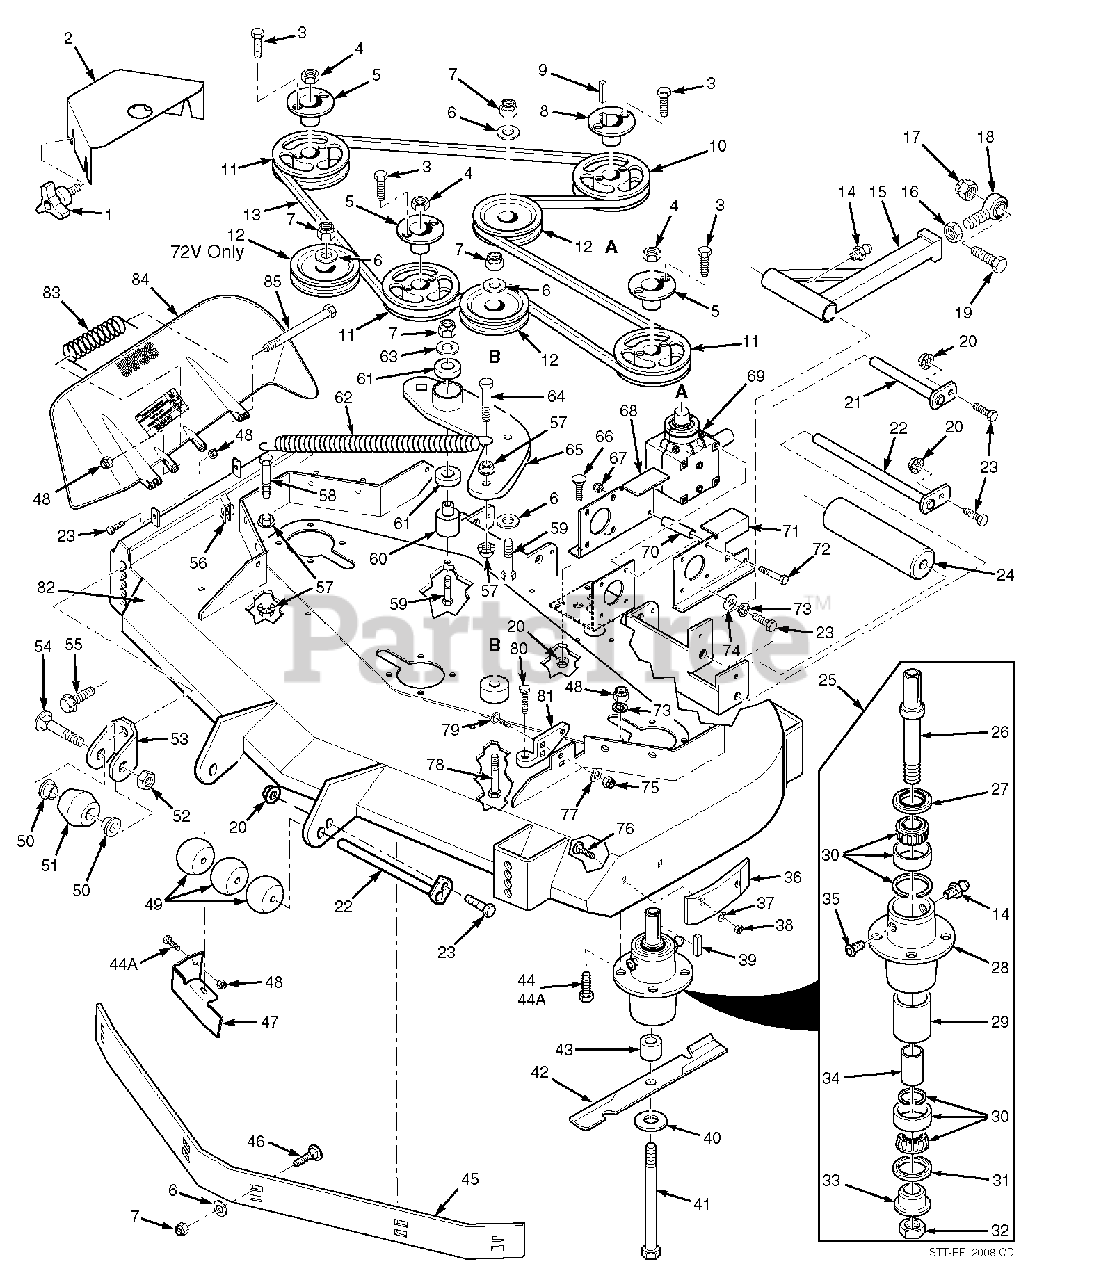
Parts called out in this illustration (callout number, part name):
1	Wing Nut, 3/8-16
2	Belt Cover
3	Bolt, Hex Head 1/4-20 x 1" Grd 8
4	Nut, 5/8-11 UNC
5	Tapered Hub, 1-1/8" Bore
6	Flatwasher, 3/8" (.391 x .938 x .105)
7	Nut, Hex Elastic Stop 3/8-16
8	Tapered Hub, 1" Bore
9	Key, 1/4 x 1/4 x 1-1/4"
10	Pulley, 6.75 O.D.
11	Pulley, 6.35 O.D.
12	Pulley, Idler
13	Belt, Cutter Deck Drive
14	Grease Fitting
15	Pusharm
16	Nut, Hex Head 5/8-18 UNF
17	Nut, Hex Elastic Stop 5/8-11
18	Rod End, 5/8" Male RH Thread
19	Bolt, Hex Head 5/8-11 x 4-1/2"
20	Nut, Hex Serrated Flange 5/16-18
21	Push Arm Shaft
22	Roller Shaft
23	Bolt, Hex Head 5/16-18 x 1-3/4"
24	Wheel, Anti-Scalp
25	Spindle Assembly
26	Spindle Shaft
27	Seal, Top
28	Spindle Housing
29	Spacer, Outside
30	Bearing Assembly
31	Seal, Bottom
32	Nut, Special 1-1/16-18
33	Spindle Bushing, Bottom
34	Spacer, Inside
35	Relief Fitting, Tapered Spindle
36	Wear Pad
37	Flatwasher, 5/16"
38	Nut, Center Lock 5/16-18
39	Key, 1/4 x 1/4 x 2"
40	Flatwasher, 5/8" Hardened
41	Bolt, Hex Head 5/8-11 x 9-1/2"
42	Cutter Blade, 21"
43	Spacer, Spindle Bottom
44	Bolt, Hex Head 5/16-18 x 1-3/4"
45	Baffle, Custom Cut 61V
45	Baffle, Custom Cut 72V
46	Bolt, Carriage 3/8-16 x 1"
47	Discharge Baffle 61V
48	Nut, Hex Elastic Stop 5/16-18 Grd 8
49	Wheel, Anti-Scalp
50	Bushing, .376 I.D. Oilite
51	Anti-Scalp Wheel
52	Locknut, 3/8-16 Center Lock
53	Anti-Scalp Wheel Bracket
54	Bolt, Carriage 3/8-16 x 4"
55	Bolt, Hex Serrated Flange 3/8-16 x 1"
56	U-Nut, 3/8-16
57	Nut, Hex Serrated Flange 3/8-16
58	Bolt, Hex Head 3/8-16 x 1-1/2"
59	Bolt, Hex Head 3/8-16 x 3"
60	Pivot, Idler - Short
61	Bearings, Ball
62	Spring, Cutter Deck
63	Flatwasher,3/8-.39 x .938 x .105 HD
64	Bolt, Hex Head 3/8-16 x 1-1/2" Grd 8
65	Idler Arm, Cutter Deck
66	Bolt, Carriage 5/16-18 x 3/4"
67	Nut, Elastic Stop 5/16-18
68	Mounting Plate, RH Gearbox
69	Gearbox Assembly, Deck Drive
70	Spacer, Gearbox Mount
71	Mounting Plate, LH Gearbox
72	Bolt, Hex Head 5/16-18 x 4-3/4"
73	Lockwasher, 5/16"
74	Flatwasher, 5/16" (.375 x .875 x .083)
75	Nut, Elastic Stop 7/16-14
76	Bolt, Carraige 5/16-18 x 3/4"
77	Flatwasher, 7/16-.500 x 1.25 x .083
78	Bolt, Hex Head 3/8-16 x 3-1/4"
79	Bolt, Carriage 7/16-14 x 1-1/4"
80	Bolt, Deck Adjust
81	Lever Assy, Deck Level
82	Cutter Deck 61 V w/Decals
83	Spring, Discharge Chute
84	Discharge Chute
85	Bolt, Hex Head 5/16-18 x 4-1/2"
